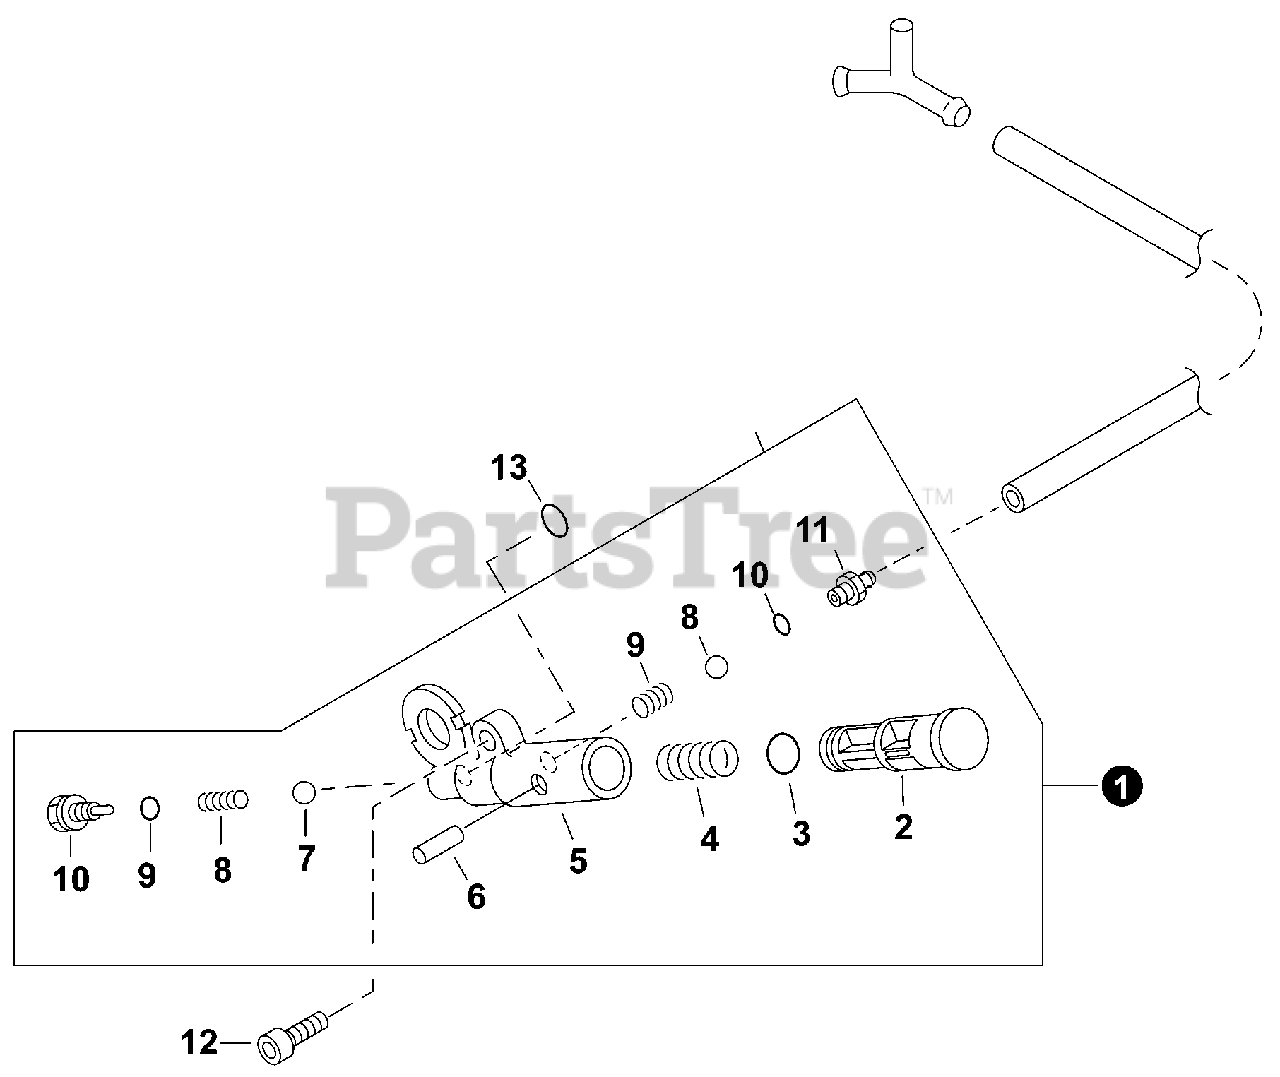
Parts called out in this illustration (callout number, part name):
1	OIL PUMP ASSY - ORANGE
1	OIL PUMP ASSY - BLACK
2	PISTON, OIL PUMP - ORANGE
2	PISTON, OIL PUMP - BLACK
3	O-RING 7 MM
5	BODY, OIL PUMP
6	PIN, SPRING 2x16
7	VALVE, BALL
8	SPRING, COMPRESSION
10	ADAPTOR, OIL PUMP
11	CONNECTOR, PIPE
12	BOLT 5x20
13	O-RING 3
